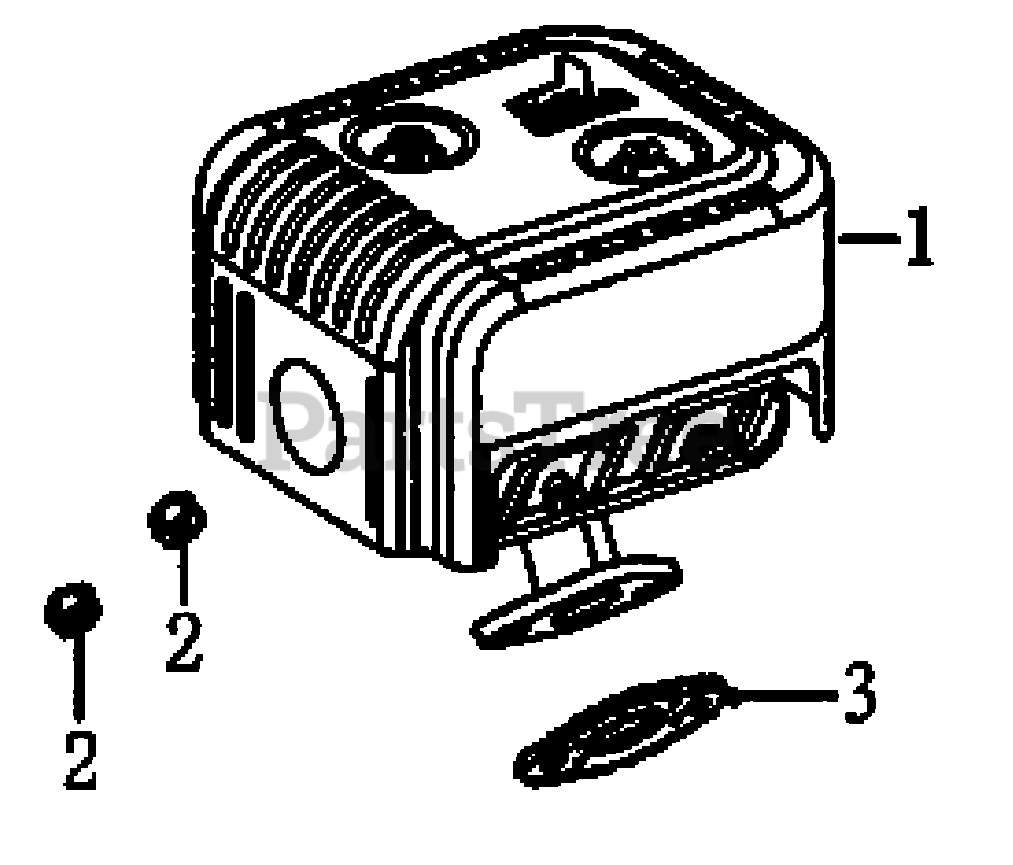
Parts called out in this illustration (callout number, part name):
1	MUFFLER ASSEMBLY
2	NUT, HEXGON
3	GASKET, MUFFLER
